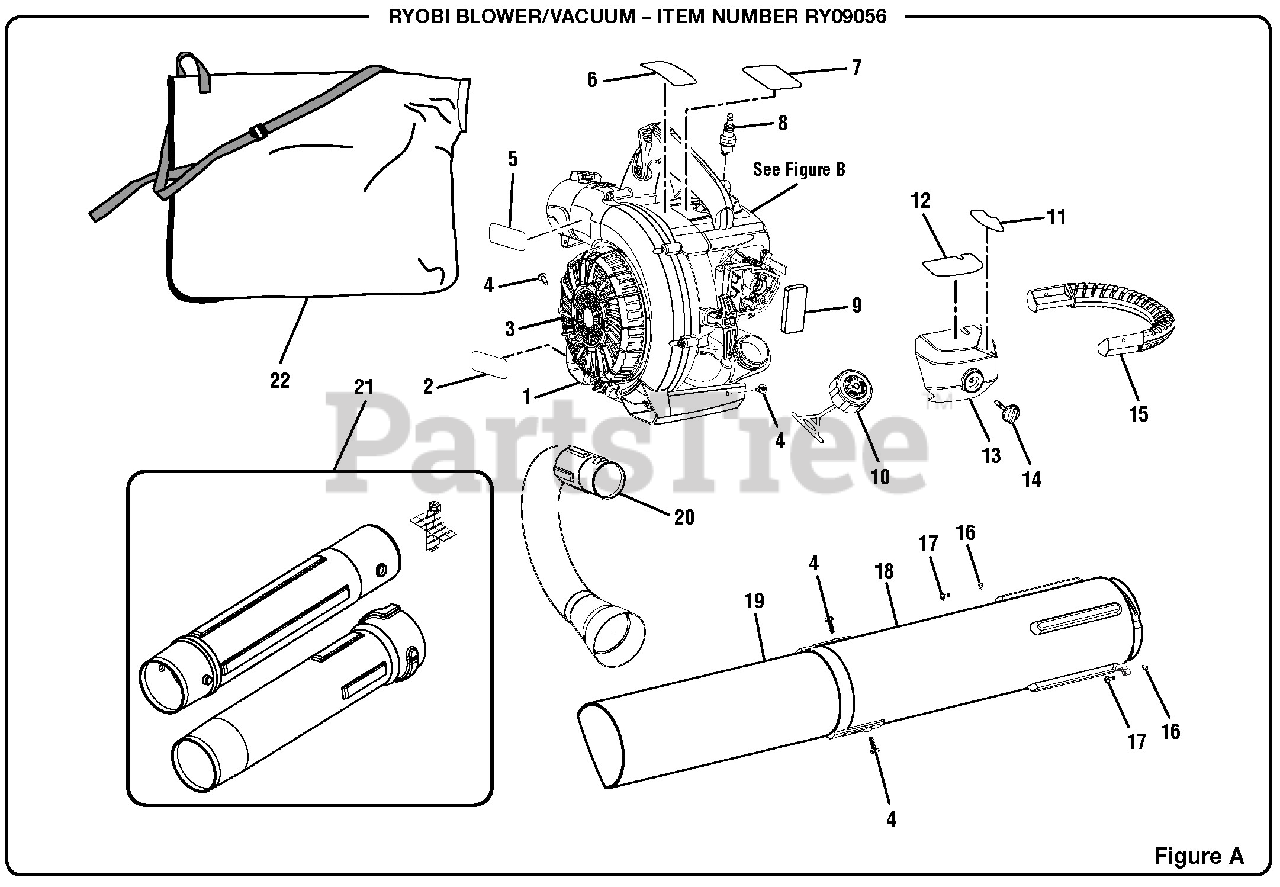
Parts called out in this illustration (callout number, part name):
1	Vacuum Door Spring
2	Combustion Label
3	Vacuum Door
4	Vacuum Tube Screw (10-14 x 1/2 in.)
5	Logo Label (Large)
6	Warning Label
7	Logo Label (Small)
8	Spark Plug (RCJ6Y)
10	Fuel Cap Assembly
11	Choke Label
12	Starting Label
13	Air Filter Cover
14	Knob
15	Vacuum Handle
17	Screw (1/4-20 x 3/4 in.)
18	Upper Vacuum Tube
19	Lower Vacuum Tube
20	Vacuum Bag Adaptor
21	Blower Tube Assembly
22	Vacuum Bag w/Shoulder Strap
